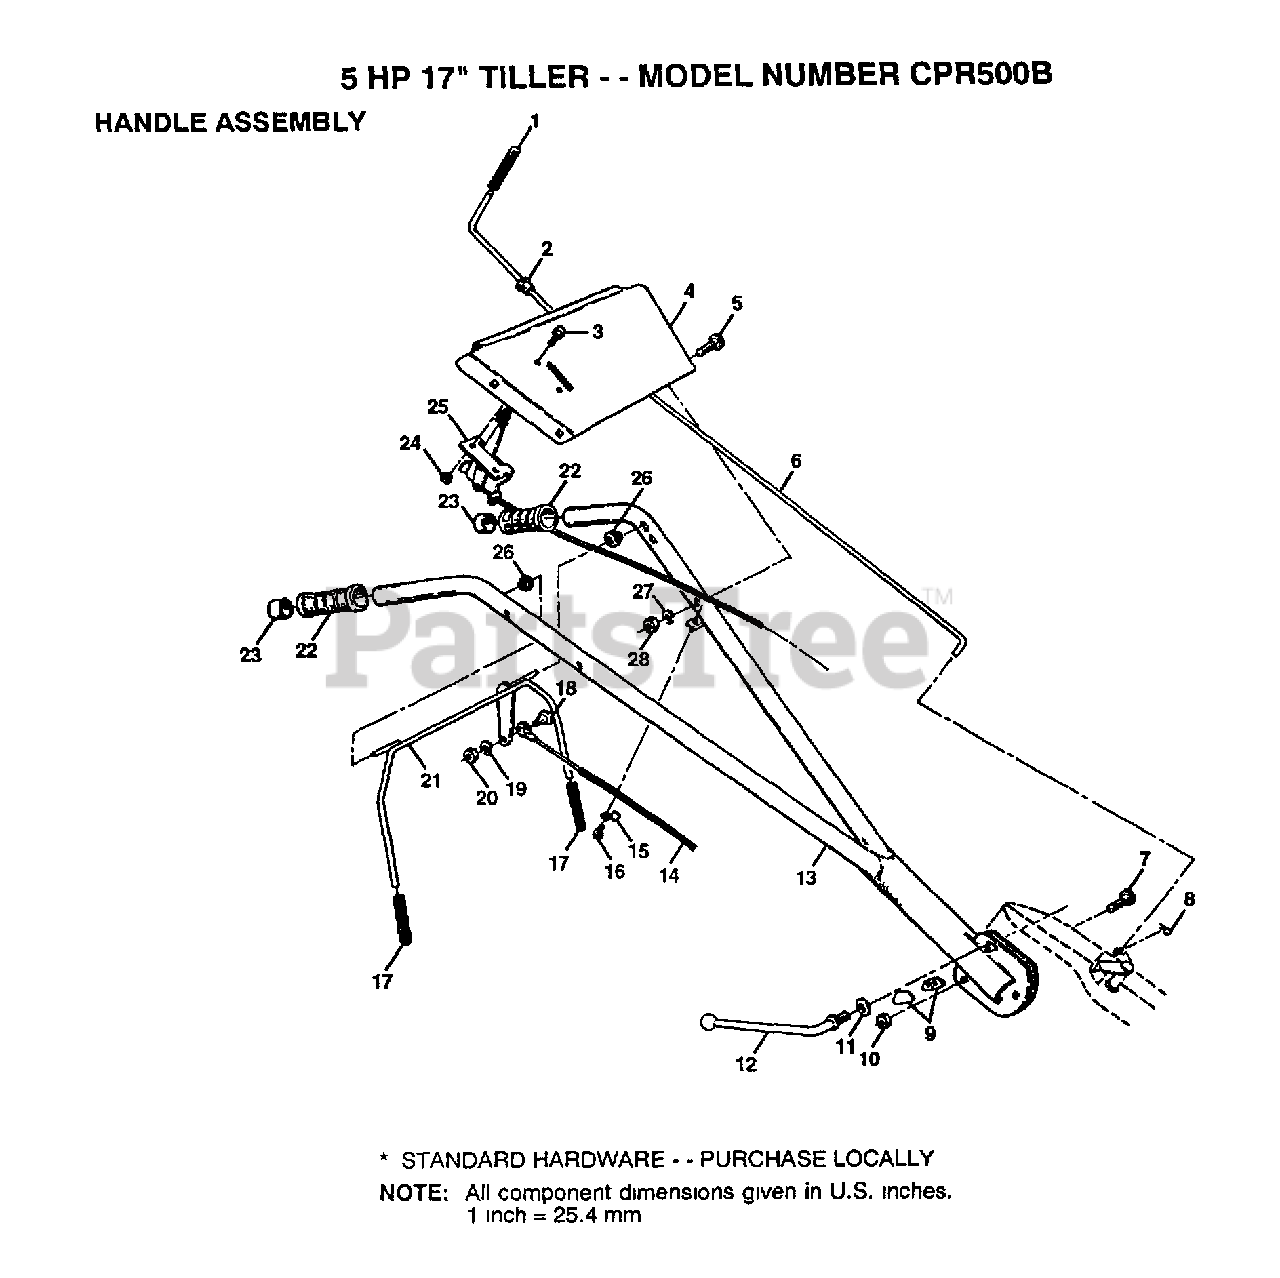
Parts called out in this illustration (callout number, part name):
1	GRIP TI
2	BUSHING
3	SCREW
5	BOLT CARRIAGE CRT
6	ROD SHIFT CRT
7	BOLT D
8	RETAINER M
9	LOCK CRT
10	LOCKNUT
11	WASHER CRT
12	LEVER LOCK CRT
14	CABLE.CLUTCH.CRT
15	CONDIUT CLIP T
17	GRIP BAR CRT
18	SHOULDER BOLT ST
19	LOCKWASHER
21	HANDLE BAR CRT
23	CAP CRT
25	"CONT,THROTTLE"
27	LOCKWASHER
